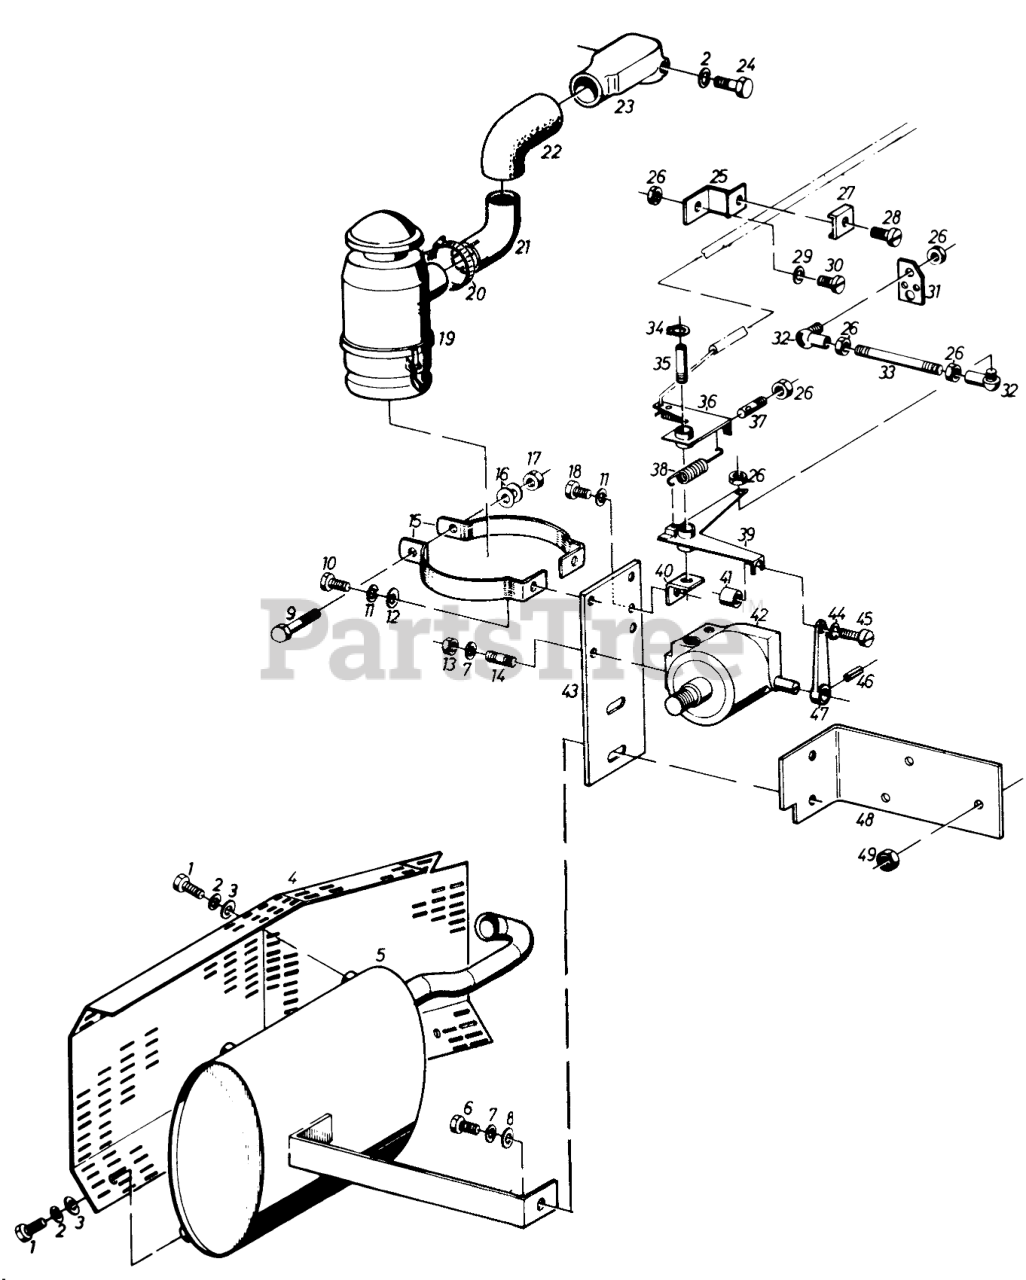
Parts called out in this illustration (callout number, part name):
1	Screw
2	Lock Washer
3	Washer
4	Muffler Grill
5	Muffler
7	Washer
8	Washer
11	Lockwasher
12	Washer
15	Clamp
16	Washer
19	Oil Bath Air Filter (BH 107)
19	Oil Bath Air Filter (OZU 17/18)
19	Oil Bath Air Filter (FX 796D)
20	Clamp
21	Intake Manifold
22	Rubber Tube
23	Intake Manifold
24	Screw
25	Bracket
27	Clamp
28	Screw
29	Lock Washer
30	Screw
31	Carburetor Lever
32	Angle Joint (W/Part 26)
33	Governor Rod
34	Grip Ring
35	Screw
36	Lever Assy
38	Spring
39	Governor Lever Assy
40	Angle
42	Governor Assy
43	Governor Support
44	Spring Washer
45	Screw
46	Pin (2.5 X 14)
47	Governor Lever
48	Support
